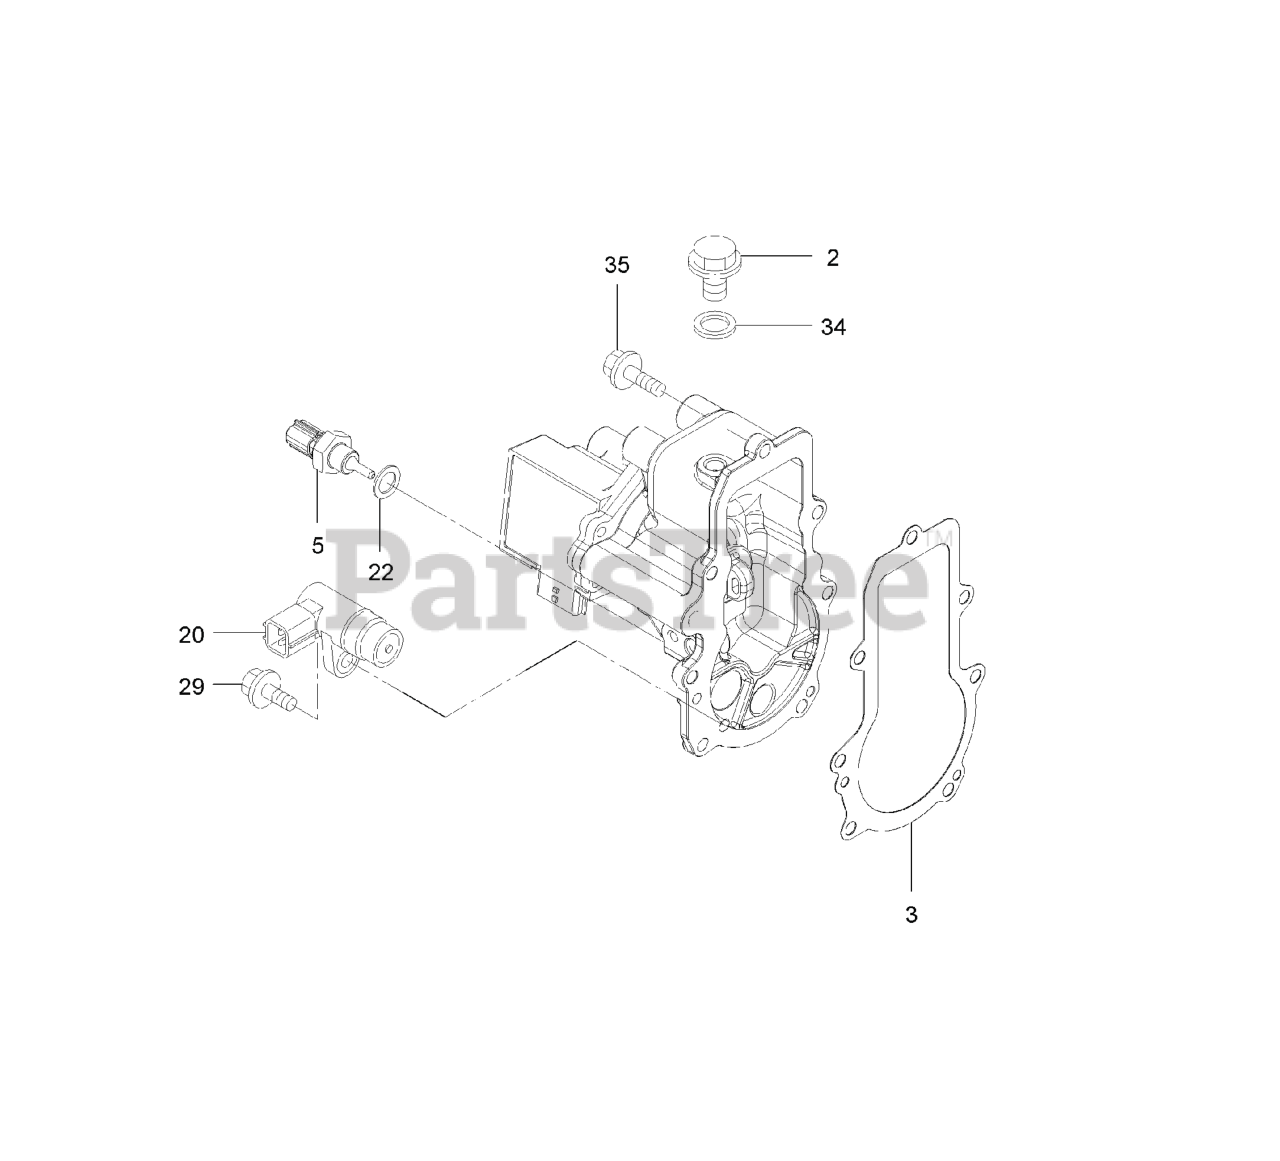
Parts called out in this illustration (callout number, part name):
5	SENSOR-OIL TEMP
22	WASHER-SEAL
34	WASHER-SEAL
